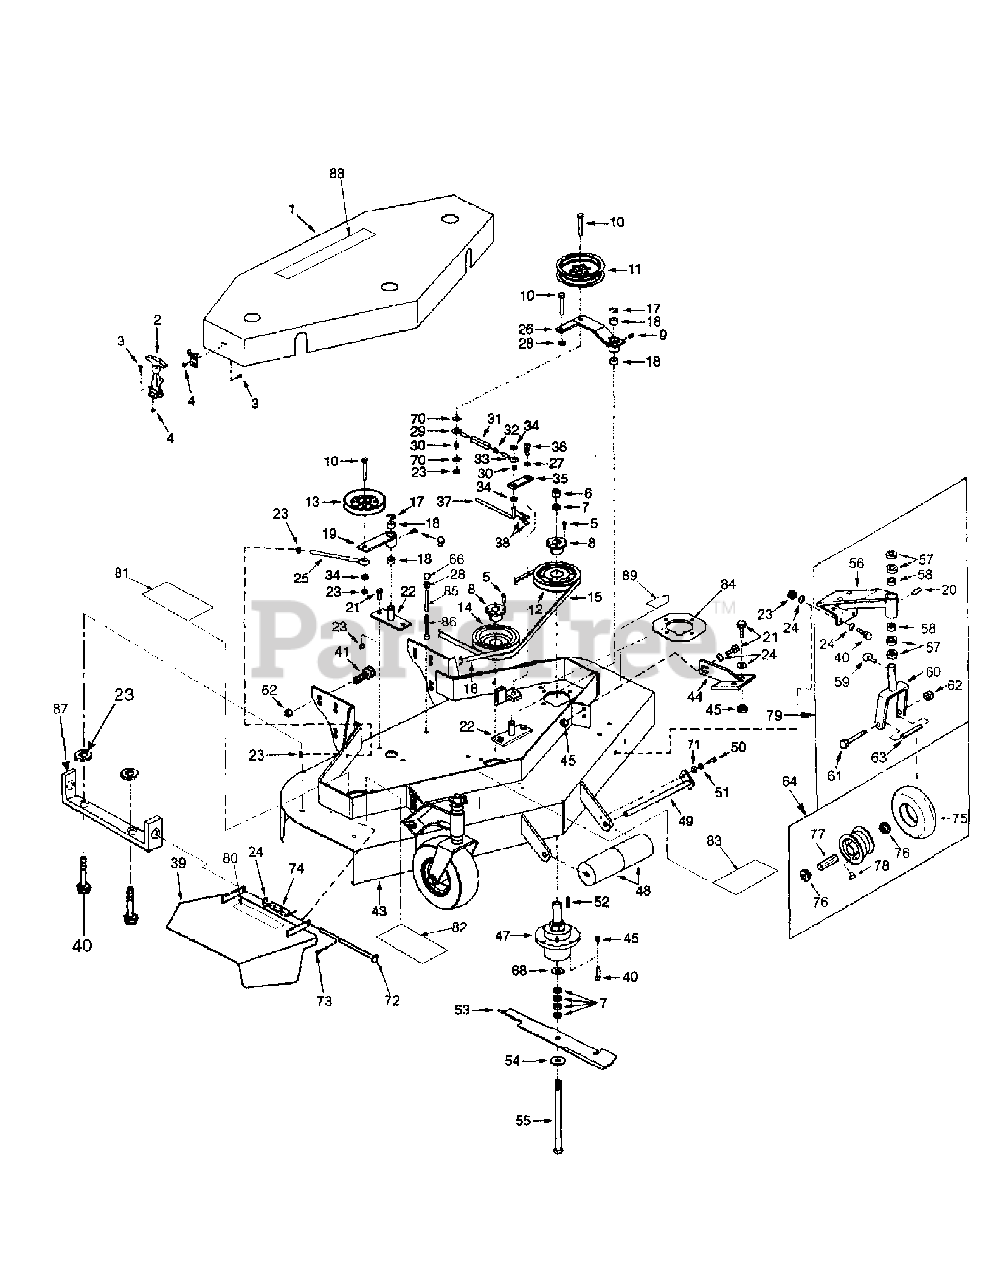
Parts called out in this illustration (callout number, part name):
1	Belt Cover
2	Latch
3	Machine Screw, #10-24 x 1/2 Rd. Hd.
4	Hex Nut, #10-24 Nylock
5	Cap Screw, 1/4-20 x 3/4 Hex Hd.
6	Hex Nut, 5/8-11
7	Blade Spacer
8	Bushing, Pulley
9	Grease Fitting, 1/4-28, 90
10	Cap Screw, 3/8-16 x 2-1/2 Hex Hd.
11	Idler, Deck Take-Up
12	Pulley, Single Belt
13	Pulley, Idler
14	Pulley, Dual Belt
15	Belt, BK90
16	Belt, BK54
17	E-Ring, External
18	Sintered Bushing
19	Pivot Arm, Deck Idler Pulley
20	Grease Fitting, 1/4-28, Straight
21	Cap Screw, 3/8-16 x 1 Hex Hd.
22	Idler Pivot
23	Hex Nut, 3/8-16 Nylock
24	Flat Washer, 3/8 Small O.D.
25	Rod, Idler Tensioner
26	Pivot Arm, Deck Take-Up Idler Pulley
27	Shim Washer, 1/2 x 3/4 x 1/16
28	Hex Nut, 3/8-16
29	Eyebolt, L.H.
30	Sleeve
31	Turnbuckle
32	Hex Nut, 5/16-18
33	Eyebolt, R.H.
34	Flat Washer, 3/8 Large O.D.
35	Clutch Link
36	Shoulder Bolt
37	Rod, Blade Clutch
38	Clip, Hairpin, 3/8-7/16
39	Discharge Chute
40	Cap Screw, 3/8-16 x 1-1/4 Hex Hd.
41	Cap Screw, 1/2-13 x 1-1/4 Hex Hd.
42	Lock Washer, 1/2 Heavy
43	Deck, 52" Walk-Behind
44	Caster Brace
45	Hex Nut, 3/8-16 Stover
46	Belt Guide
47	Spindle Assembly
48	Roller, Anti-Scalping
49	Axle
50	Cap Screw, 5/16-18 x 3/4 Hex Hd.
51	Lock Washer, 5/16
52	Key, 1/4 x 1/4 x 2
53	Blade, Rotary 18
54	Flat Washer, 5/8
55	Cap Screw, 5/8-11 x 9-1/2 Hex Hd.
56	Caster Bracket
57	Caster Spacer
58	Bushing, Caster Bracket
59	Lynch Pin
60	Caster Yoke
61	Cap Screw, 1/2-13 x 5-1/2 Hex Hd.
62	Hex Nut, 1/2-13 Nylock
63	Sleeve, Caster Wheel Bearing
64	Tire and Wheel Assembly, 9 x 3.50 - 4
65	Cap Screw, 3/8-16 x 5 Hex Hd.
66	Protective Cap
68	Flat Washer, 1-1/2 x 5/8 x .055
69	Flat Washer, 3/8 Heavy
70	Flat Washer, 5/16 USS
71	Flat Washer, 5/16
72	Deflector Pin Ass'y
73	Cotter Pin 1/8" x 1"
74	Torsion Spring
75	Tire, Caster Wheel
76	Bearing Retainer, Caster Wheel
77	Roller Bearing, Caster Wheel
78	Grease Fitting
79	Caster Assembly
80	Decal, "Width Cut"
81	Decal, Rotating Blade
82	Decal, Warning Safety
83	Decal, Warning Shield
84	Plate, Spindle Backing
85	Spacer, Belt Guard
86	Bolt, Carriage 3/8-16 x 1
87	Bracket, Deflector
88	Label, Cutter Deck
89	Decal, Danger
